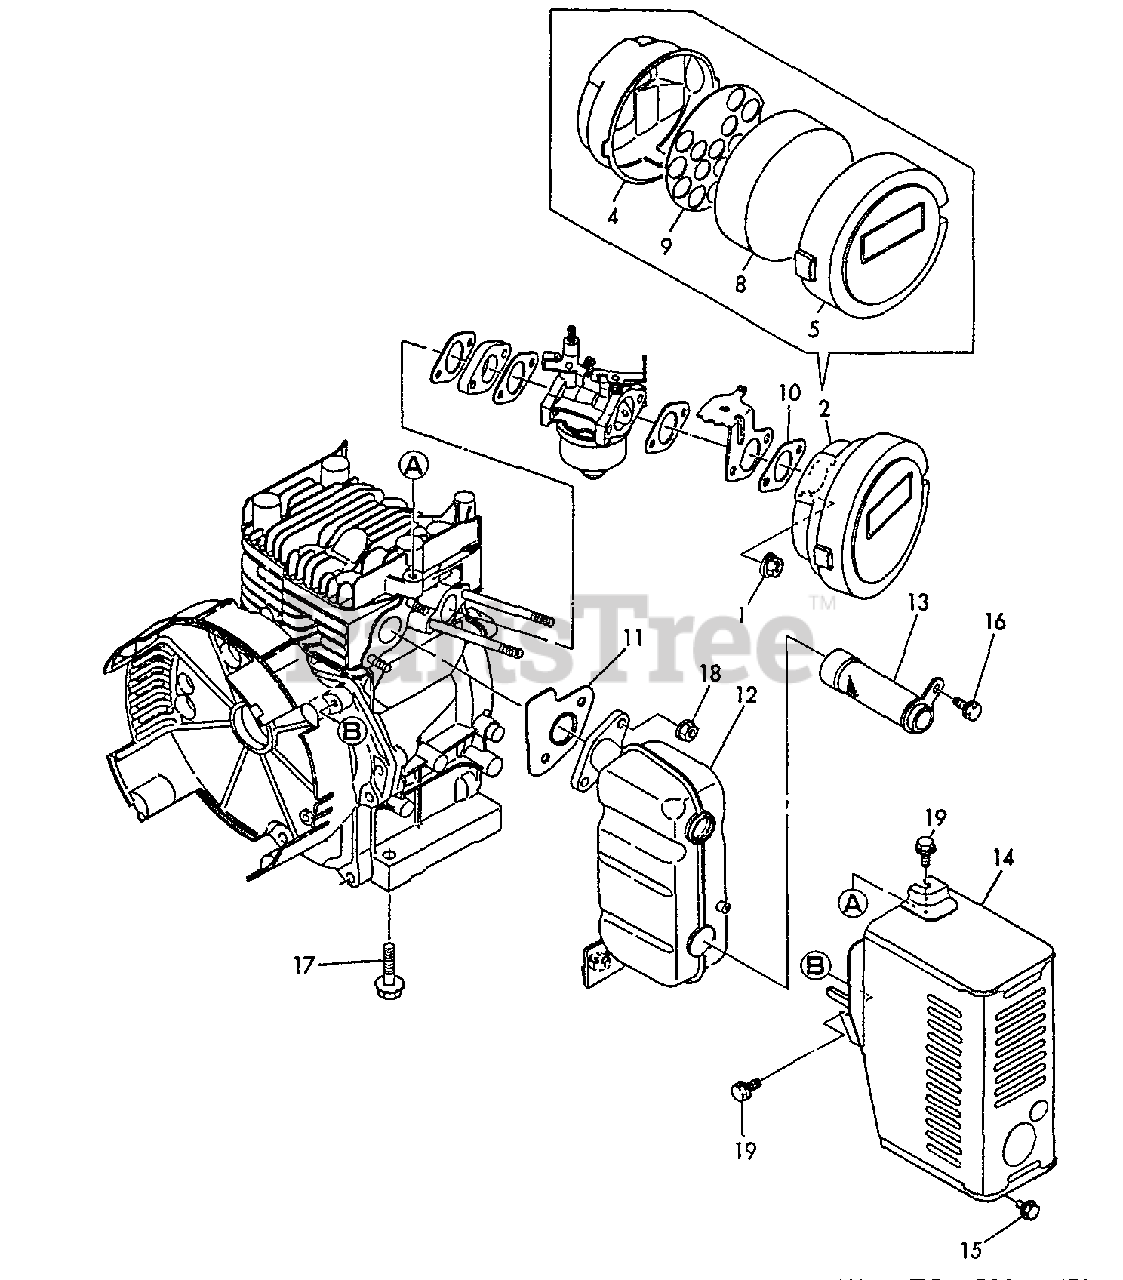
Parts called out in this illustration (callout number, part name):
1	U-NUT M6
2	CLEANER ASSY, AIR
4	CASE, AIR FILTER
5	COVER, AIR FILTER
8	FILTER, AIR
9	HOLDER, ELEMENT
10	GASKET, INTAKE
11	GASKET, EXHAUST
12	MUFFLER
13	SCREEN, SPARK ARRESTER
14	COVER, MUFFLER
15	BOLT - 6×8 -- PLATED
16	BOLT - 6×10 -- PLATED
17	BOLT - 8×30 -- PLATED
18	U-NUT M6
19	BOLT - 6×8 -- PLATED
